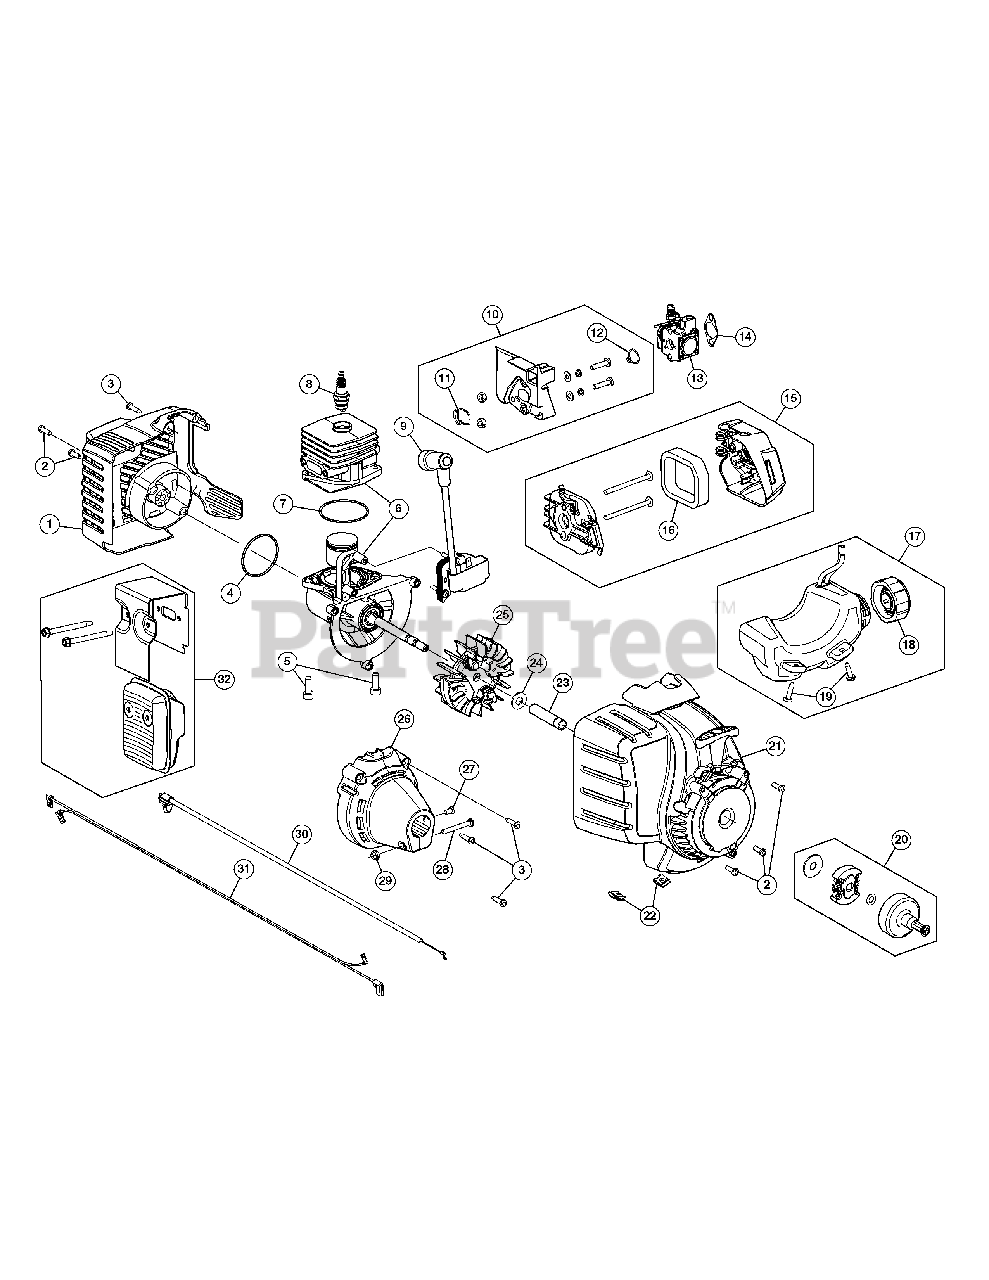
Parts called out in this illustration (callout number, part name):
1	Rear Cover Assembly (Incl. 2 & 3)
2	Cover Screw
3	Rear Housing Screw
4	O-Ring
5	Crankcase Bolt
6	Short Block Assembly (Incl. 4, 5, 7 - 9 & 23 - 25)
7	Crankcase O-Ring
8	Spark Plug
9	Module Assembly
10	Insulator Assembly (Incl. 11 & 12)
11	Insulator O-Ring
12	Carburetor O-Ring
13	Carburetor
14	Air Cleaner Gasket
15	Aircleaner Cover Assembly (Incl. 16)
16	Aircleaner Filter
17	Fuel Tank Assembly (Incl. 18 & 19)
18	Fuel Tank Screw
19	Fuel Tank Cap
20	Clutch Assembly
21	Starter Housing (Incl. 2 & 22)
22	U-shaped Nut
23	Spacer
24	Washer
25	Flywheel Assembly
26	Clutch Cover (Incl. 3)
27	Anti-rotation Screw
28	Clamp Screw
29	Clamp Nut
30	Throttle Cable
31	Lead Wires
32	Muffler Assembly
